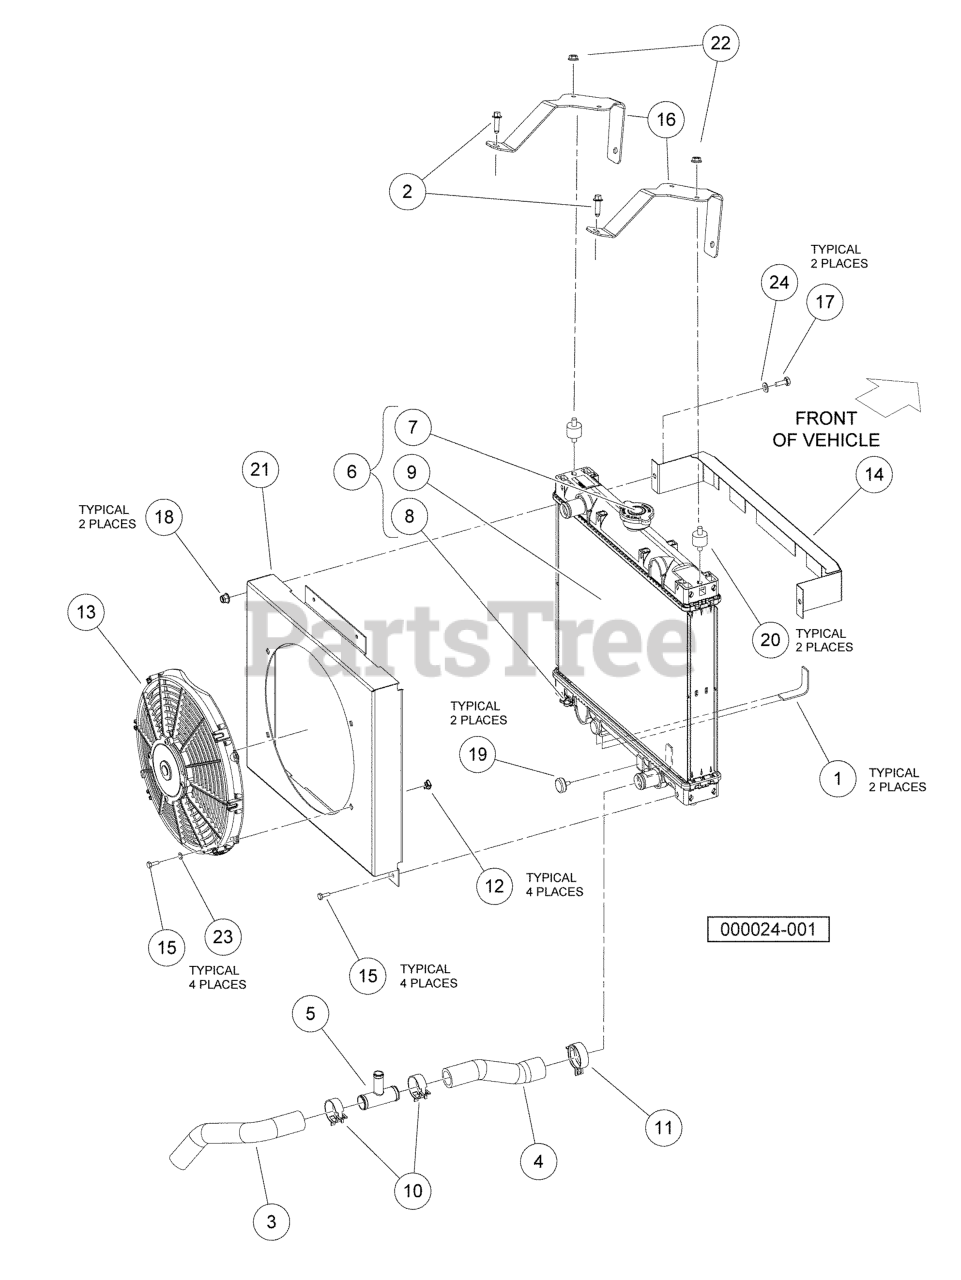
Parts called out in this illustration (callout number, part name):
1	BOX INS.BULK
2	SCREW-M8 X 1.25 30, TRI, HX F
3	HOSE, COOLANT LOWER PIPE
4	HOSE, COOLANT LOWER RAD
5	TEE, COOLANT FILL
6	EXCHANGER, ENGINE COOLANT
7	CAP, RADIATOR, NON PRESSURE
8	DRAIN COCK, RADIATOR
9	Radiator
10	CLAMP, HOSE, CTB 35MM
11	CLAMP, HOSE, CTB 38MM
12	NUT, SELF RETAINING
13	FAN, COOLING 12 IN ELECT
14	GUARD, RADIATOR-TOP
15	BOLT, M6 X 1 X 16 LOCTITE
16	BRACKET, UPPER RADIATOR MOUNT
17	BOLT, M8 X 1.25 X 20
18	LOCK NUT, FLG M8 X 1.25 NYLON
19	BUMPER, 13MM STUD
20	ISOLATOR, TWIN STUD, RADIATOR
21	SHROUD, RADIATOR FAN
22	NUT, M8-1.25 FLANGED HEX
23	WASHER, M6
24	WASHER, M8 HARD
